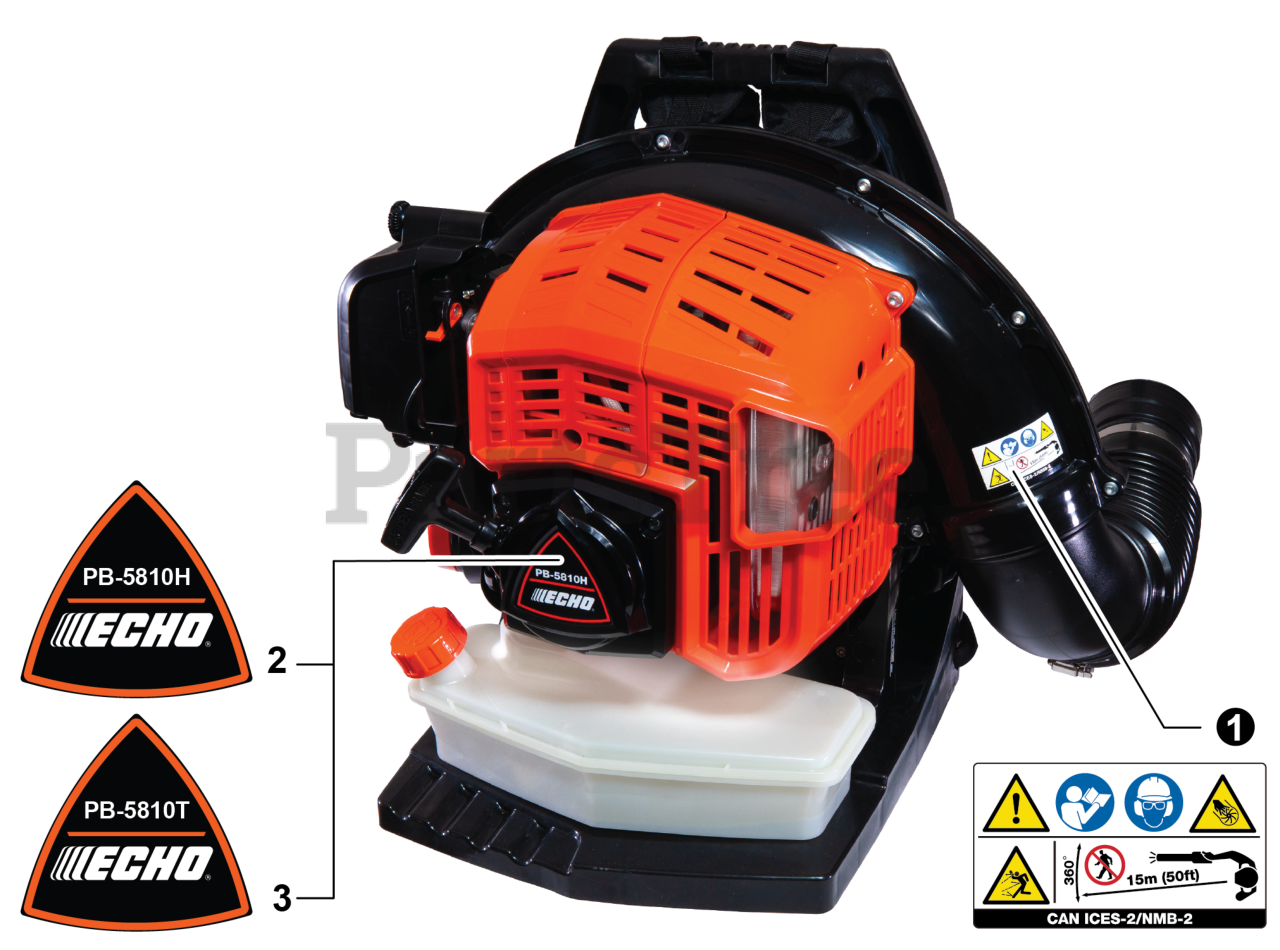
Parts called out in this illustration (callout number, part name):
1	LABEL - CAUTION
2	LABEL - RECOIL STARTER PB-5810H
3	LABEL - RECOIL STARTER PB-5810T
